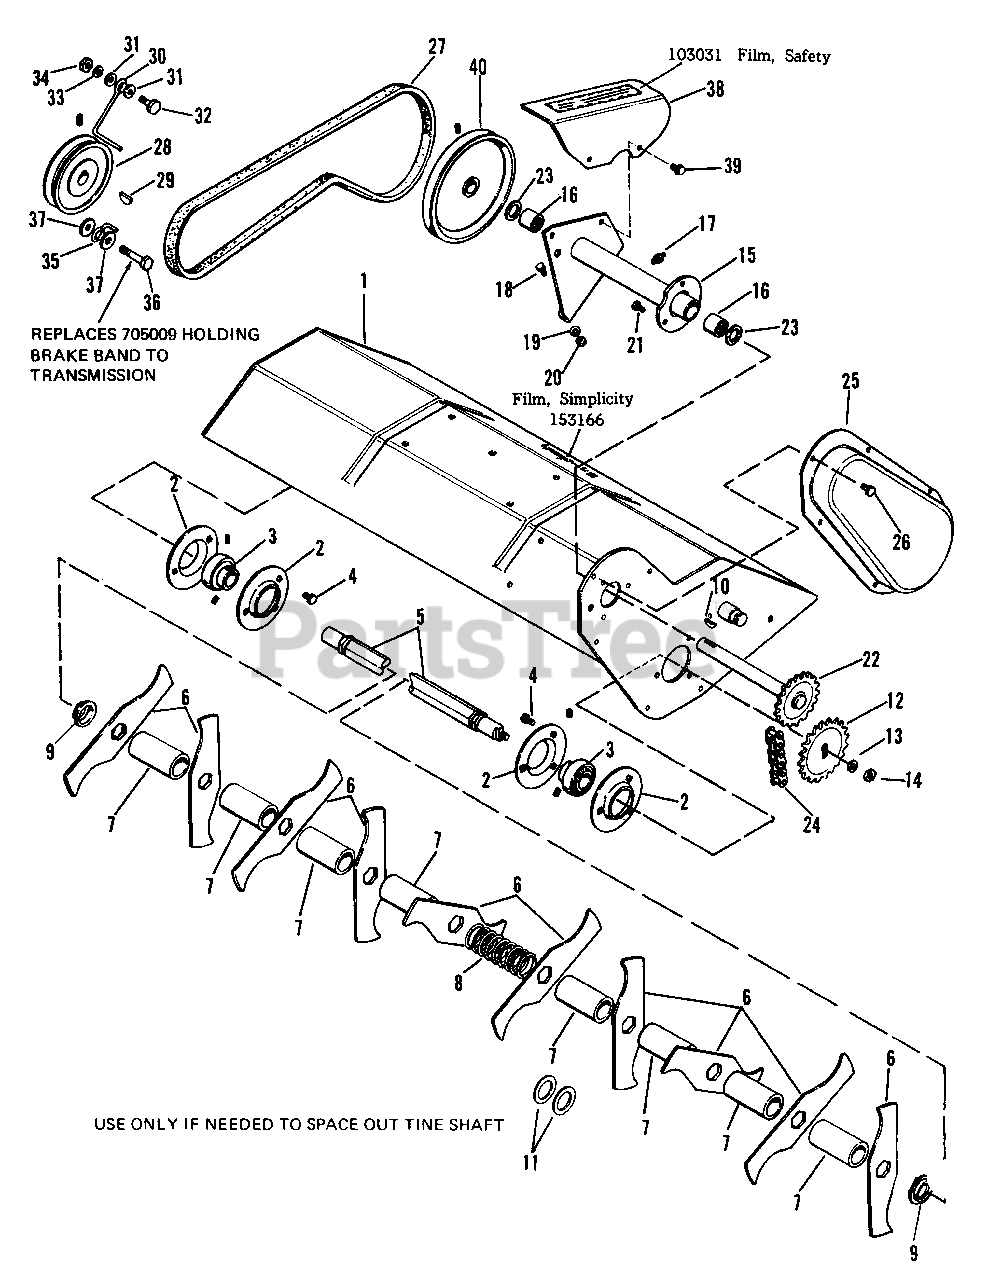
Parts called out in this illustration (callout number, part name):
1	Housing Assembly
2	Bearing Flange
4	Thread Forming Screw, 5/16"-18 x 1/2" lg.
5	Tine Shaft
8	Compression Spring
10	Key Woodruff 3/16" x 3/4"
13	Plain Washers, 5/16"
14	Hex Nut, Full, 3/8"-16
15	Bearing Housing Assembly
16	Needle Bearings
17	Grease Fitting
18	Hex Capscrew, 5/16"-18 x 5/8" lg.
19	Lock Washer 5/16"
20	Hex Nut, Full, 5/16"-18
21	Hex Screw, Washer Hd., 1/4"-20 x 3/8" Taptite
22	Drive Shaft Assembly
25	Chain Guard
26	Hex Screw, Washer Hd., 1/4"-20 x 3/8" lg. Taptite
27	V-BELT, 49.1"
29	Key, Woodruff 3/16" x 3/4"
30	Belt Stop
31	Plain Washer, 1/4"
32	Hex Capscrew, 5/16"-18 x 7/8" lg.
33	Lock Washer, 5/16"
34	Hex Nut, Full 5/16"-18
36	Hex Capscrew, 3/8"-16 x 1-3/4" lg.
37	Plain Washer, 5/16"
38	Belt Guard
39	Thread Forming Screw, 5/16"-18 x 3/8" lg.
